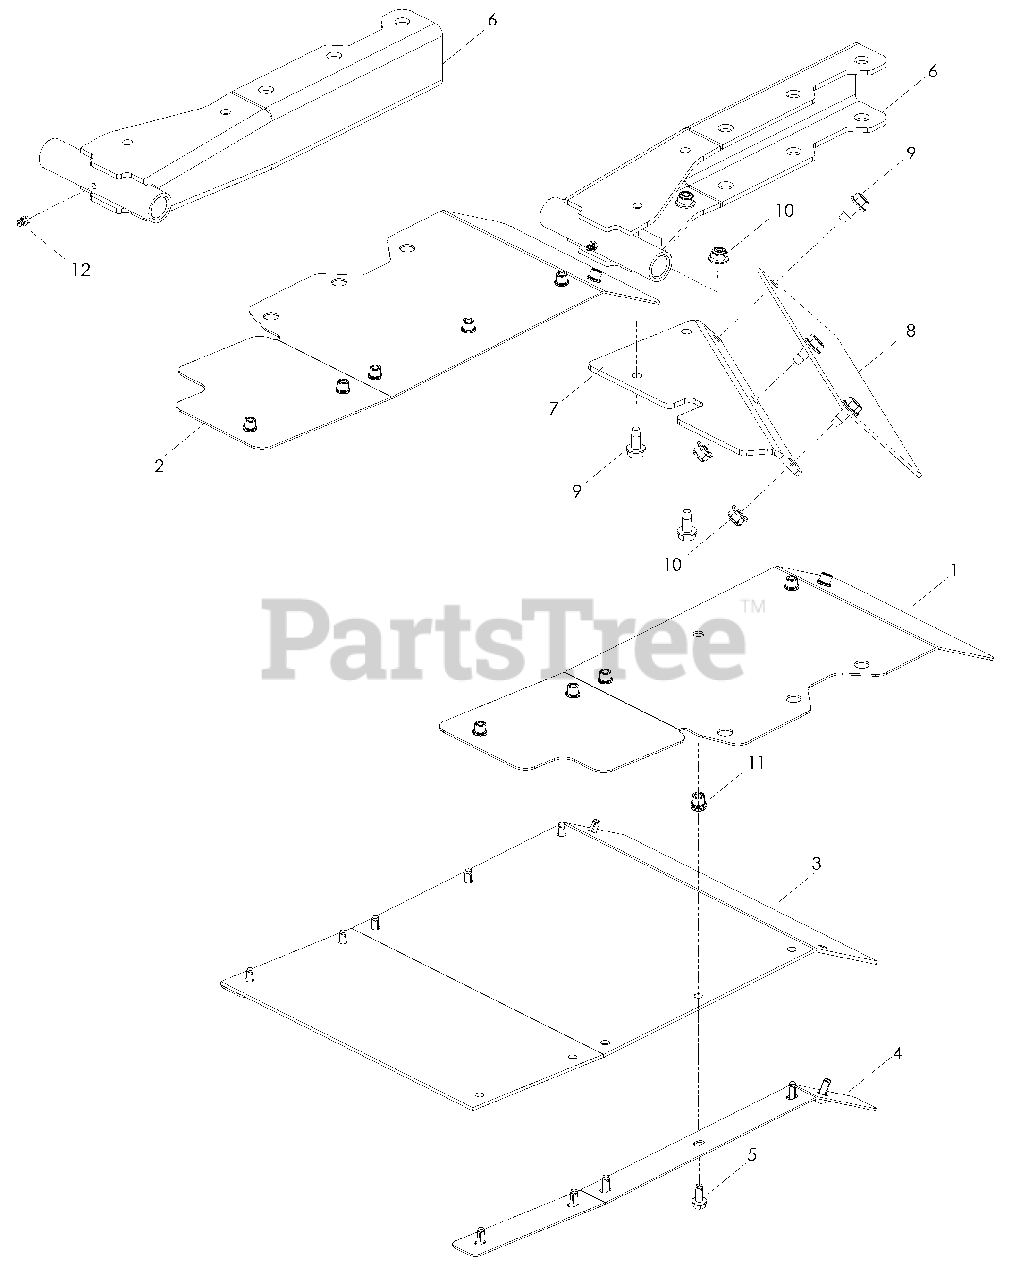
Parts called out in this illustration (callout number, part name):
1	Guard Debris, Lt
2	Guard Debris, Rt
3	Guard, Rubber
4	Strap, Guard
5	Screw, 1/4-20 x 5/8, Trdroll
8	Guard, Rubber, Small
9	Bolt 5/16-18 x 3/4 Trd Frm
10	Nut 5/16-18 Flange Nyloc
11	Insert 1/4-20 Knurled
12	Zerk
